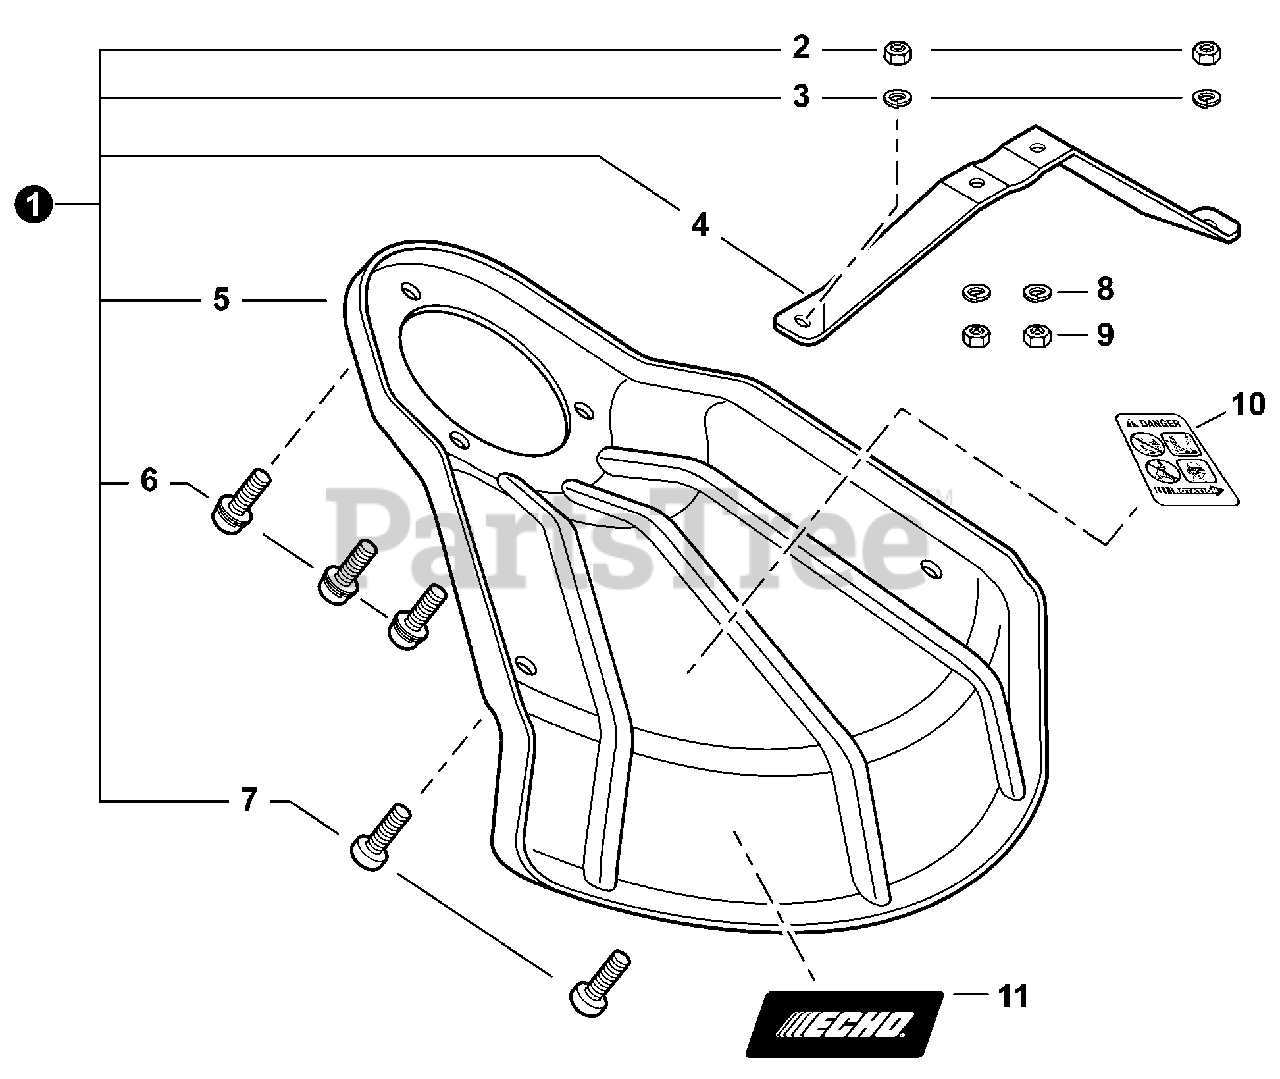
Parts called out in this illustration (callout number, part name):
1	SHIELD ASSY, METAL DEBRIS
2	NUT M5
3	WASHER, SPRING 5
4	BRACKET, SHIELD MOUNTING
5	SHIELD, METAL DEBRIS
6	BOLT, TORX 5×10
7	BOLT, TORX 5×8
8	WASHER, SPRING 5
9	NUT M5
10	LABEL, DANGER
11	LABEL, ECHO
